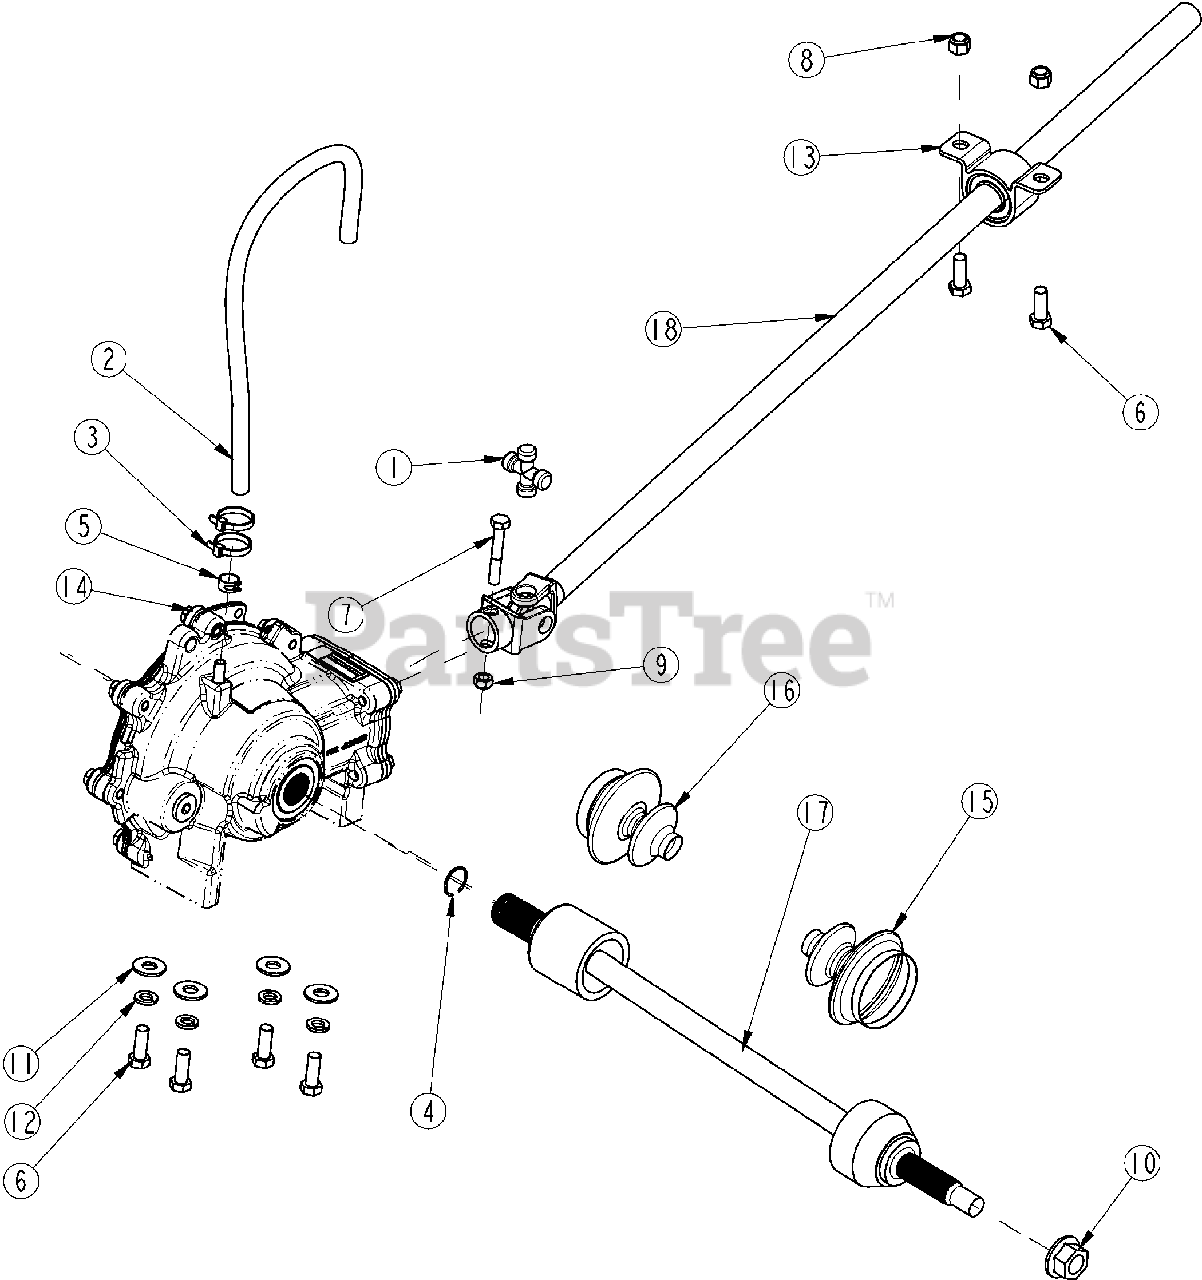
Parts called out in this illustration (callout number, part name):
1	CROSS & BRG KIT
2	VENT HOSE 17.5LG 4X4 GBOX
3	CABLE TIE 2 DIA MIN - BLK
4	SPRING CIR CLIP .95ODX.063WIRE
5	CLAMP PINCH FOR .50 OD HOSE
6	HHCS 3/8-16X1 GR5
7	HHCS 5/16-18X2 GR5
8	NUT LOCK 3/8-16 NYLON INSERT
9	NUT HEX NYLOCK 5/16-18 PLT
10	NUT HEX M16X1.5 TOP LOCK PLT
11	WASHER FLAT 3/8 USS PLT
12	WASHER LOCK SPRING 3/8 PLT
13	PILLOW BLOCK BEARING TRUCK
14	FRONT DIFFERENTIAL W/ELE CLTCH
15	OUTER BOOT KIT W/ 2 CLAMPS
16	INNER BOOT KIT W/2 CLAMPS
17	FRONT AXLE SHAFT STANDARD
18	DRIVELINE 4X4 NT/ST
